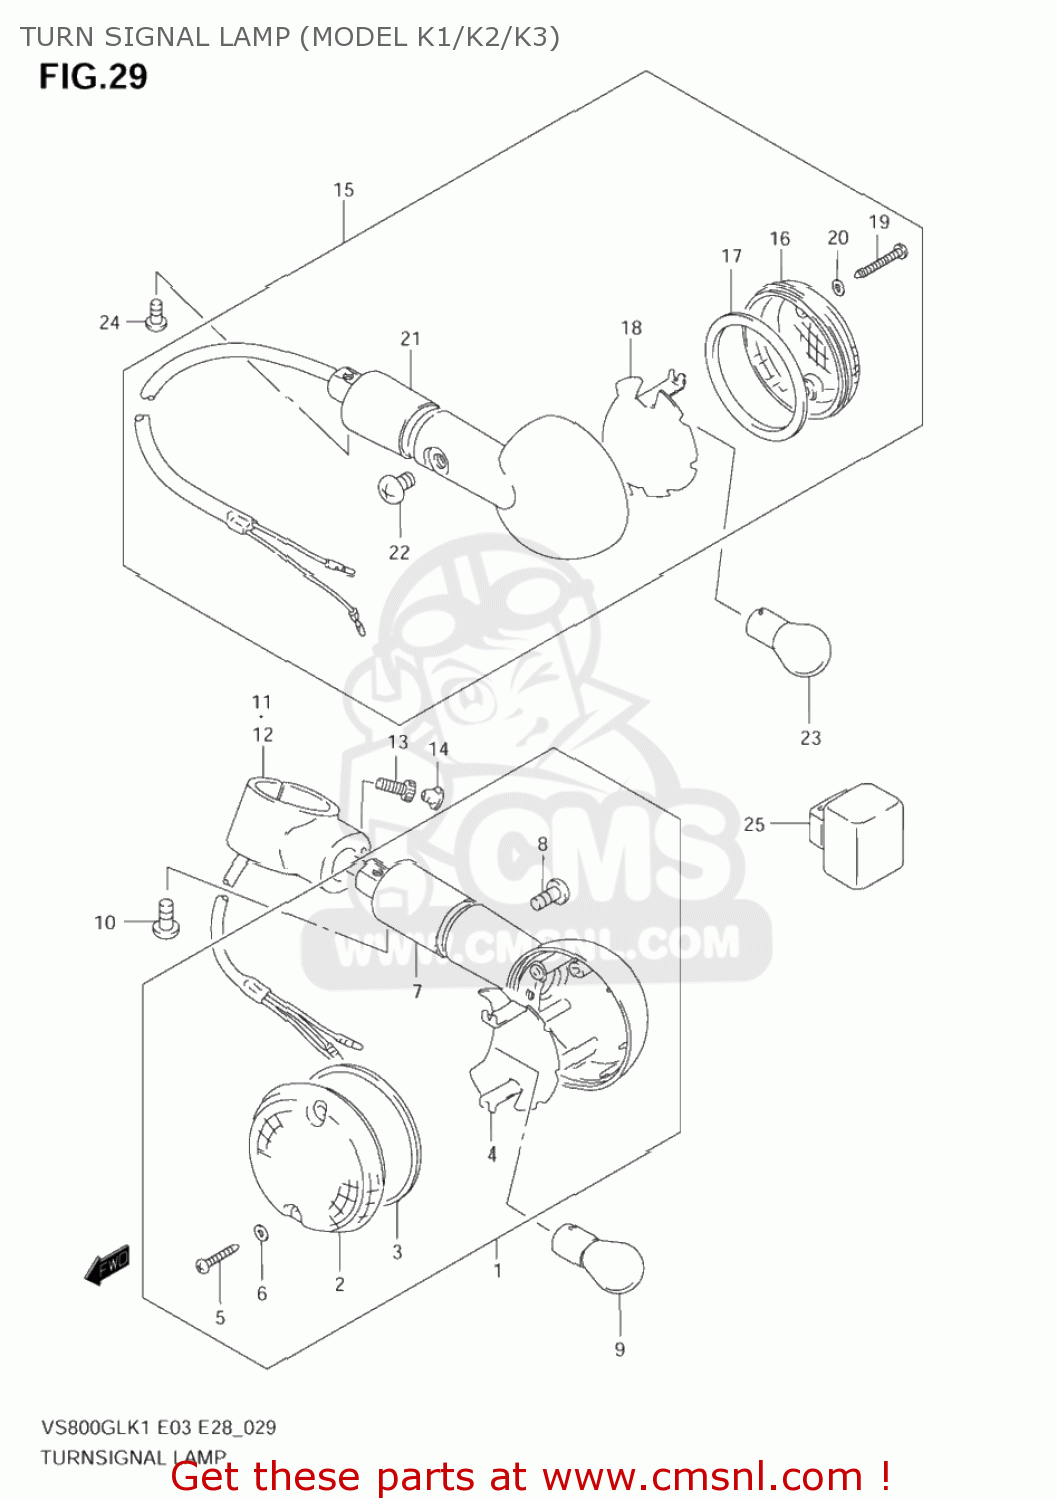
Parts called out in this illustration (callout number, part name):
1	LAMP ASSY,FR TURN SIGNAL
2	LENS
3	GASKET (NAS)
4	REFRECTOR
5	SCREW
6	GASKET (NAS)
7	STAY,TURNSIGNAL LAMP
8	SCREW
9	BULB(12V21/5W)
10	SCREW
11	BRACKET,FR TURNSIGNAL LAMP,R
12	BRACKET,FR TURNSIGNAL LAMP,L
13	BOLT
14	CAP(OD:10)
15	LAMP ASSY,FR TURN SIGNAL
16	LENS
17	GASKET (NAS)
18	REFRECTOR
19	SCREW
20	GASKET (NAS)
21	STAY,TURNSIGNAL LAMP
22	SCREW
23	BULB(12V21W)
24	SCREW
25	RELAY ASSY
